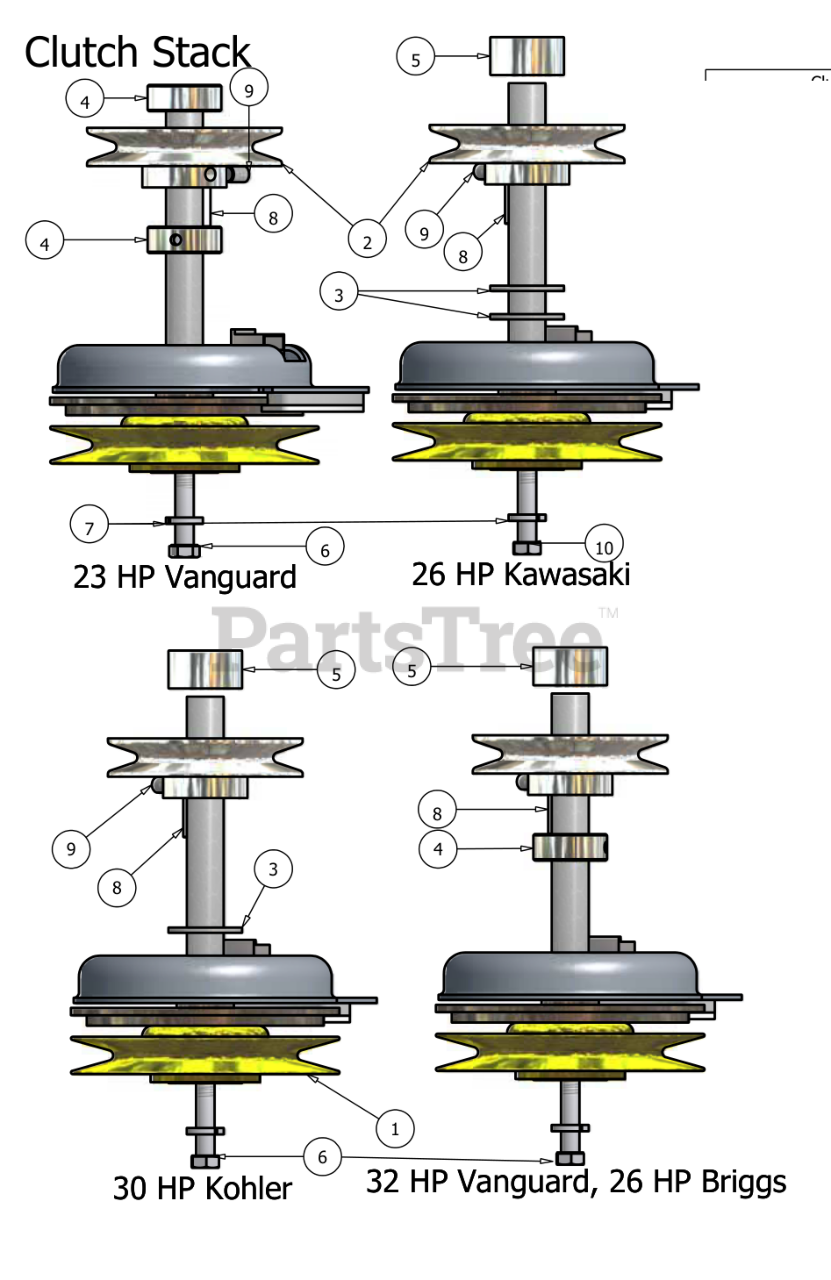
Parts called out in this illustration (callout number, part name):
1	Clutch Assembly
2	4 3/4" Motor Pulley
3	1 1/8" Flat Spacer
4	1 1/8" Collar Spacer
5	1.125 ID X.625 Spacer
6	|7/16" x 2 1/2"Fine Thread Bolt
7	7/16" Lock Washer
8	| 1/4" x 1" Key
9	3/8" Set Screw
10	10mm x 552 Bolt
